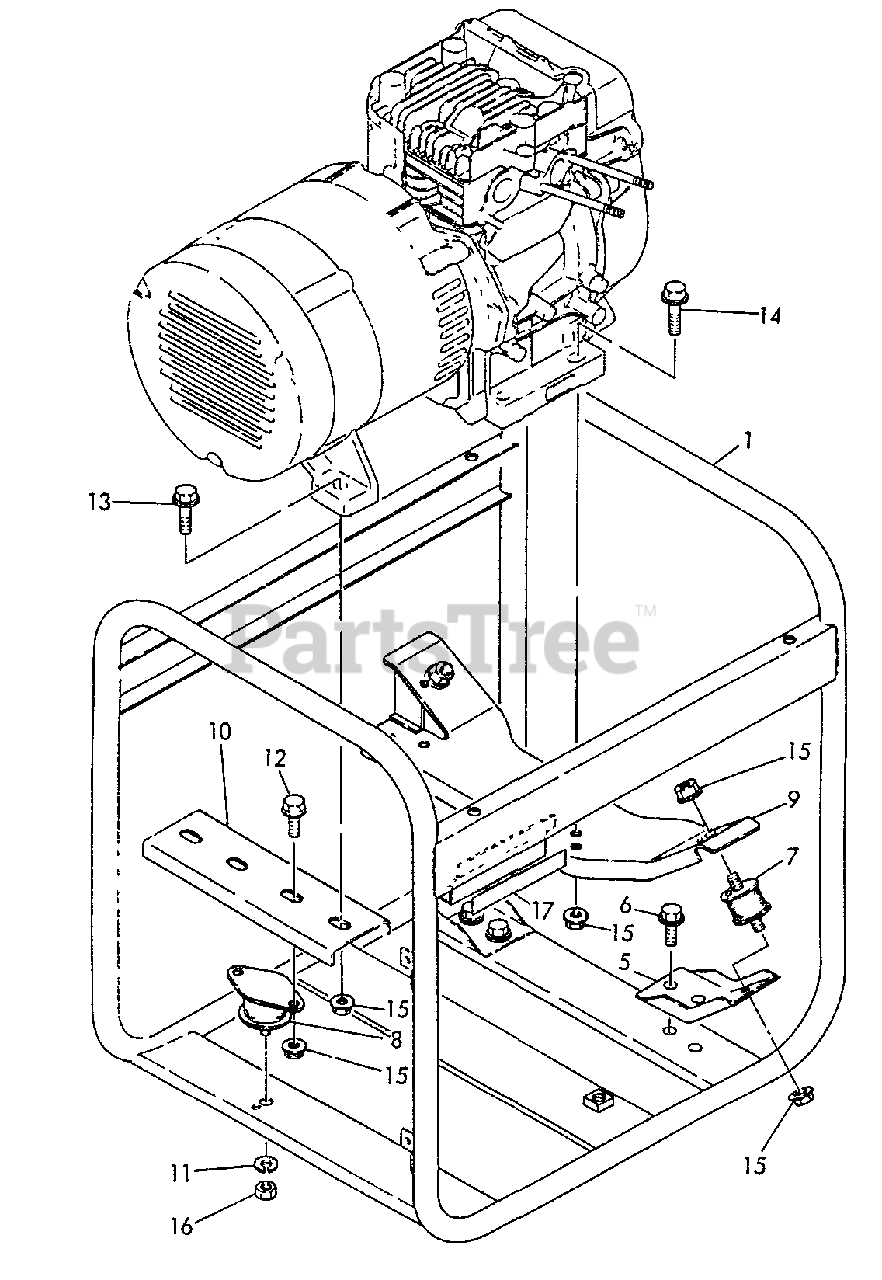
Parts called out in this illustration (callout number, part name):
1	FRAME
5	DAMPER STAY, LOWER
6	BOLT - 8X16 -- PLATED
7	DAMPER, FRONT
8	DAMPER, REAR
9	STAY, DAMPER
10	STAY, REAR DAMPER
11	LOCKWASHER - 10
12	BOLT - 8X20 -- PLATED
13	BOLT - 8X30 -- PLATED
14	BOLT - 8X38 -- PLATED
15	NUT - 8
16	NUT - 10
17	SHEET, FRAME
